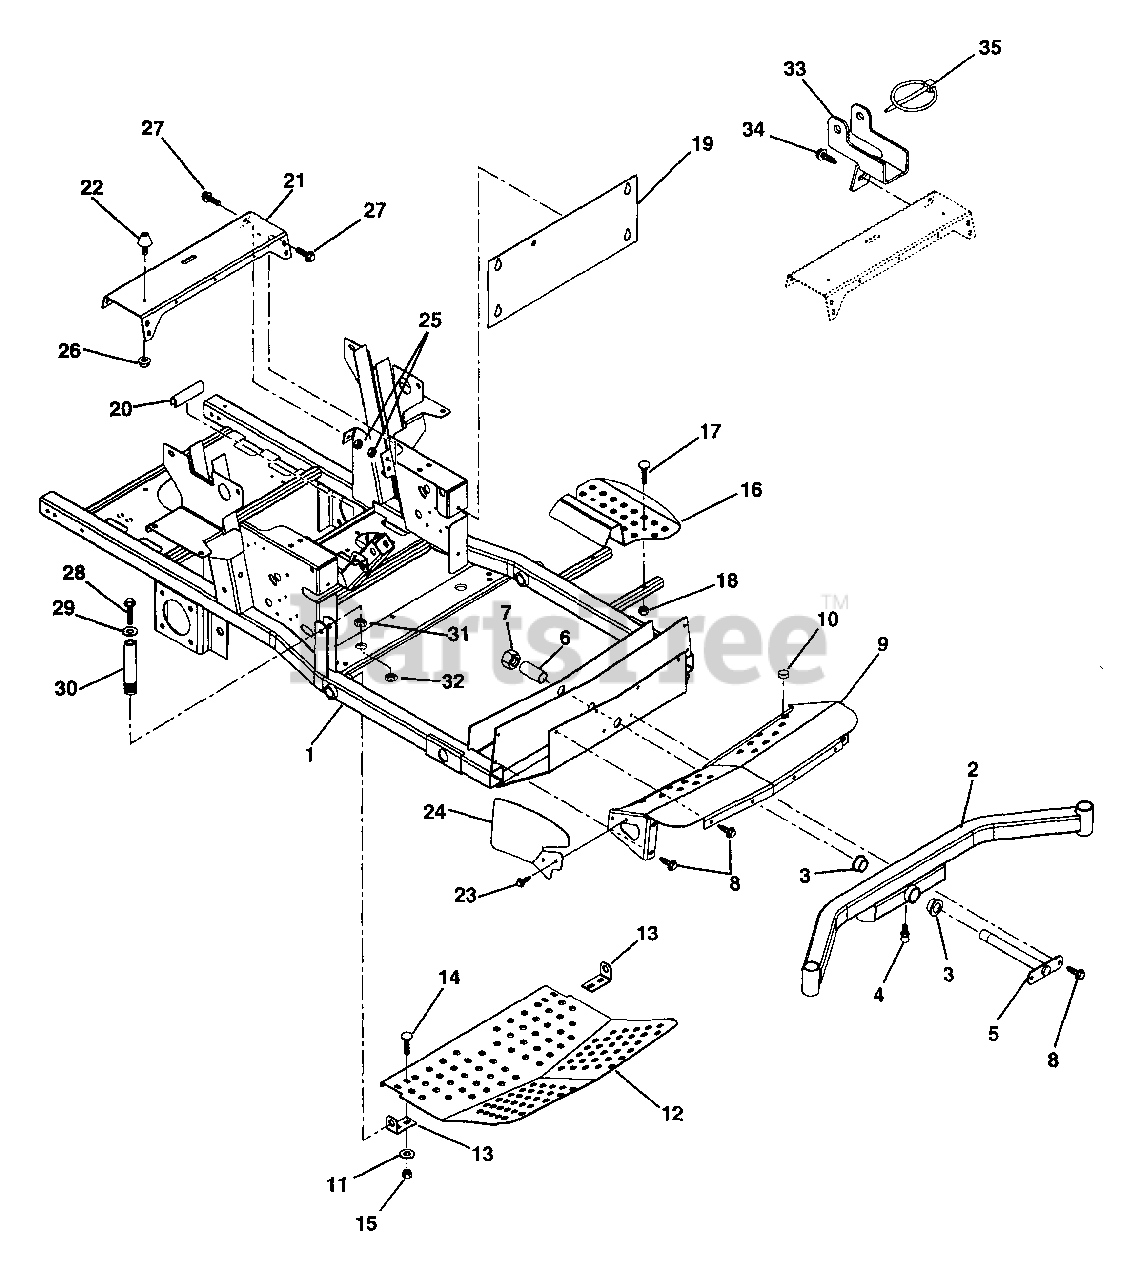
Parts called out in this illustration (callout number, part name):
1	FRAME SHORT WHEELBASE (ORANGE)
2	WMT, FRONT AXLE - ORANGE
3	BSHG-FLG1.020X1.385X.75X1.75NY
4	FTG-LUBE .25-28X.256 YWZC
5	PIN - AXLE
6	SPACER 1.009 X 1.250 X 4.23
7	NUT-LK-NYL 1.0-14 YWZC
8	@SCR-TAP .38-16X.75 HWH TR YWZ
9	COVER - AXLE (ORANGE)
10	BUTTON BUMPER
11	@WSHR-FL-STL.38X.875X.083 YWZC
12	PANEL - INSPECTION (ORANGE)
13	MOUNT, INSPECTION PANEL(BLACK)
14	@BLT-RDHDSQNK .38-16X1.00 G2YZ
15	@NUT-LK-NYL .38-16 YWZC
16	STEP - INGRESS (ORANGE)
17	@BLT-RDHDSQNK .31-18X1.50 G5YZ
18	@NUT-LK-CTR .31-18 YWZC
19	PLATE - KICK (ORANGE)
20	STRIP, COWL
21	CHANNEL - CROSS (ORANGE)
22	BUMPER, RUBBER CONE,STUD MOUNT
23	@SCR-TAP .25-20X.50 HWH TR YWZ
24	GUARD, FOOT - ORANGE
25	NUT-RTNR .375-16X.37
26	@NUT-SPNLK-FLG .312-24 YWZC
27	BLT-SERHFWH .375-16X1.0 YWZC
28	BLT-HEX .50-20X1.00 GR5 YWZC
29	@WSHR-FL-STL.531X1.06X.095YWZC
30	POST
31	NUT-JAM .75-16 YWZC
32	NUT-JAM CTRLK .75-16 YWZC
33	BRACKET, SEAT LOCK
34	@SCR-TAP .25-20X.50 HWH TR YWZ
35	PIN-LOK .31X2.00
